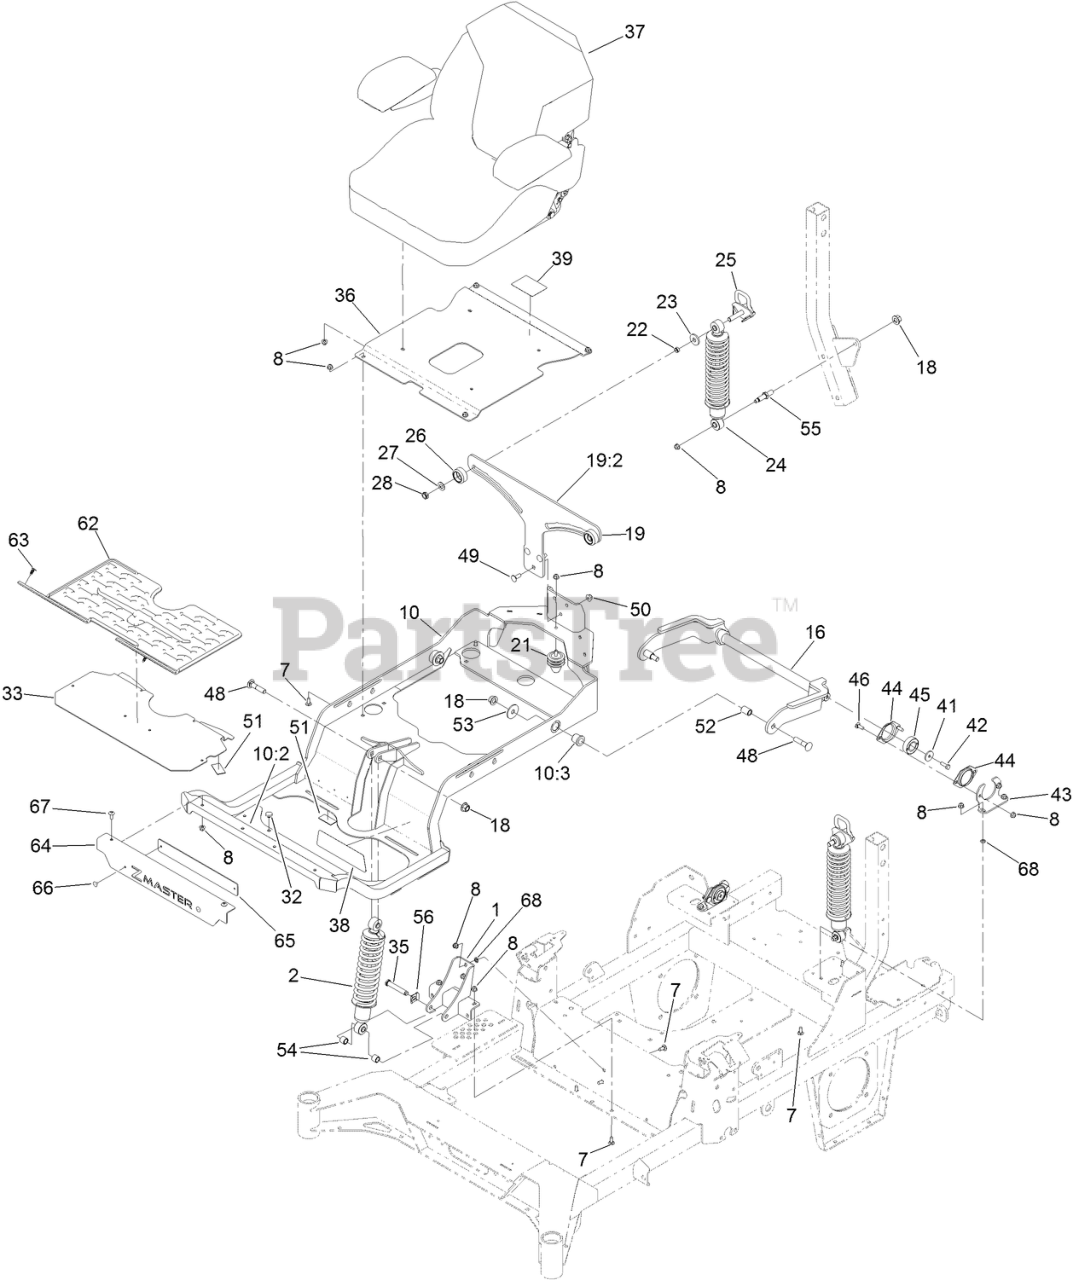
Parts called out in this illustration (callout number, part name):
1	MOUNT-SHOCK, LOWER [BLACK]
2	SHOCK ASM-FRONT
7	SCREW-CARR
8	NUT-HF, NI
10	SUBFRAME ASM
10:2	DECAL-DANGER
10:3	BUSHING-FLANGE
16	ARM-TRAILING
18	NUT-LOCK
19	BRACKET-MOUNTING
19:2	DECAL-ADJUSTMENT, RIDE
21	ISOLATOR
22	BEARING-SLEEVE
23	WASHER-PLASTIC
24	SHOCK/SPRING ASM
25	CAM LOCK ASM
26	KNOB-LOCK, CAM
27	WASHER-ADJUSTING
28	NUT-HEX
32	BUMPER
33	FLOORPAN
35	PIN-CLEVIS
36	PAN-SEAT
37	SEAT ASM-STANDARD
38	DECAL-MYRIDE
39	DECAL-SERVICE AID
41	WASHER-FLAT
42	SCREW-HH, THREAD LOCKING
43	BRACKET-BEARING
44	HOUSING-BEARING, FLANGE
45	BEARING
46	BOLT-CARR
48	SCREW-CARR
49	SCREW-CARR
50	NUT-HF, NI
51	PAD-RUBBER
52	SPACER-ALUMINUM
53	WASHER-THRUST
54	SPACER-TUBE
55	BOLT-SHOULDER
56	CLIP-PIN
62	FLOORMAT-MYRIDE
63	PLUG-PLASTIC
64	PLATE-BADGE
65	PLATE-BACKER
66	RIVET-POP
67	SCREW-TORX
68	NUT-PUSH
